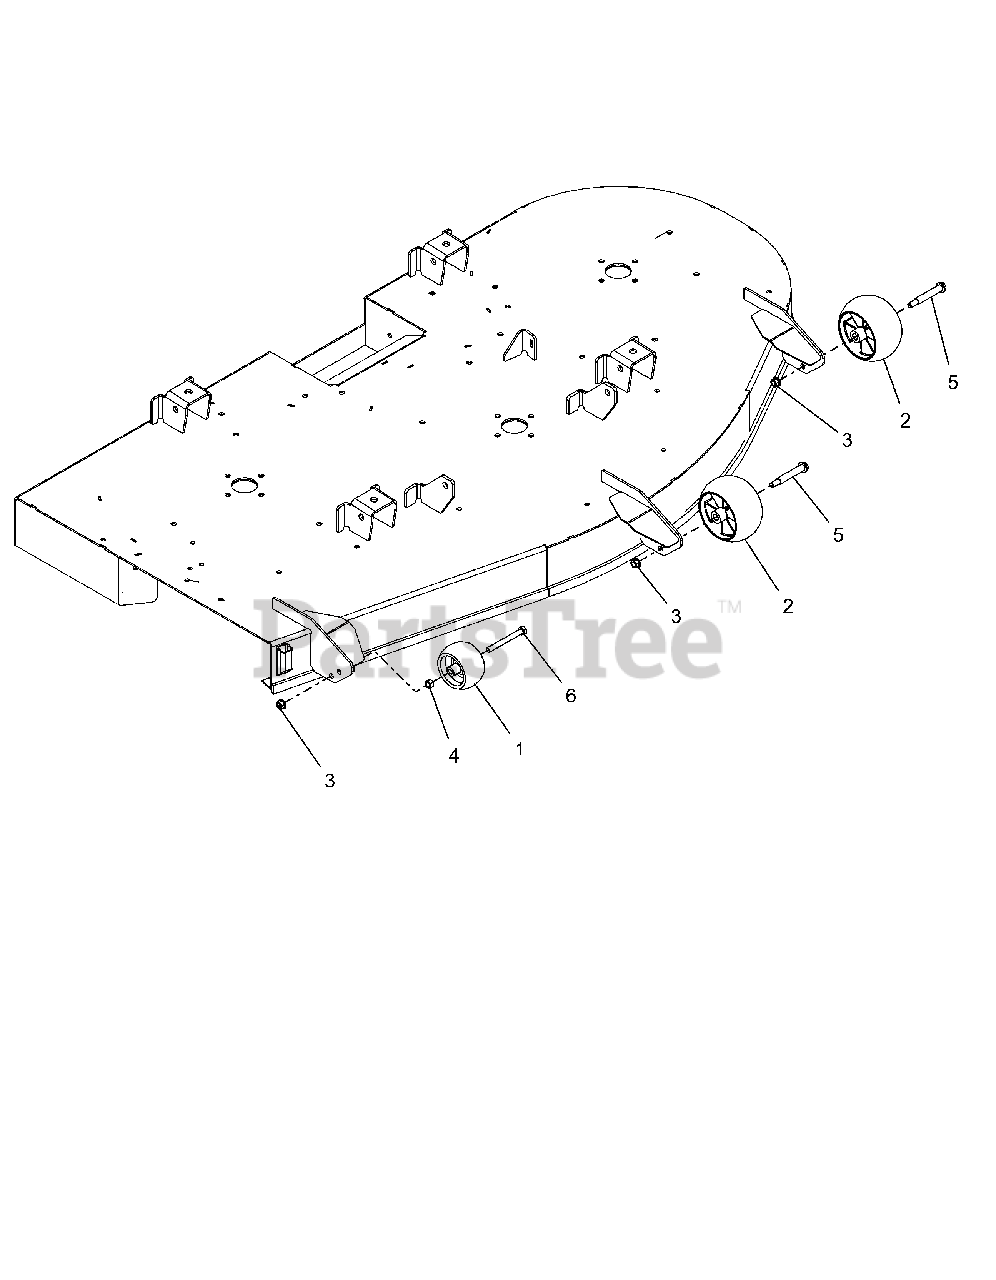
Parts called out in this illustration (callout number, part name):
2	ANTI-SCALP WHEEL - 5X OS
3	NUT-LK-TOP-FLG .38-16 ZC120
4	@NUT-HEX .38-16 YWZC
5	BLT-SHLDR .38-16X2.50 HWH G5
6	BLT, HEX .38-16X3.50 G5 ZCC
